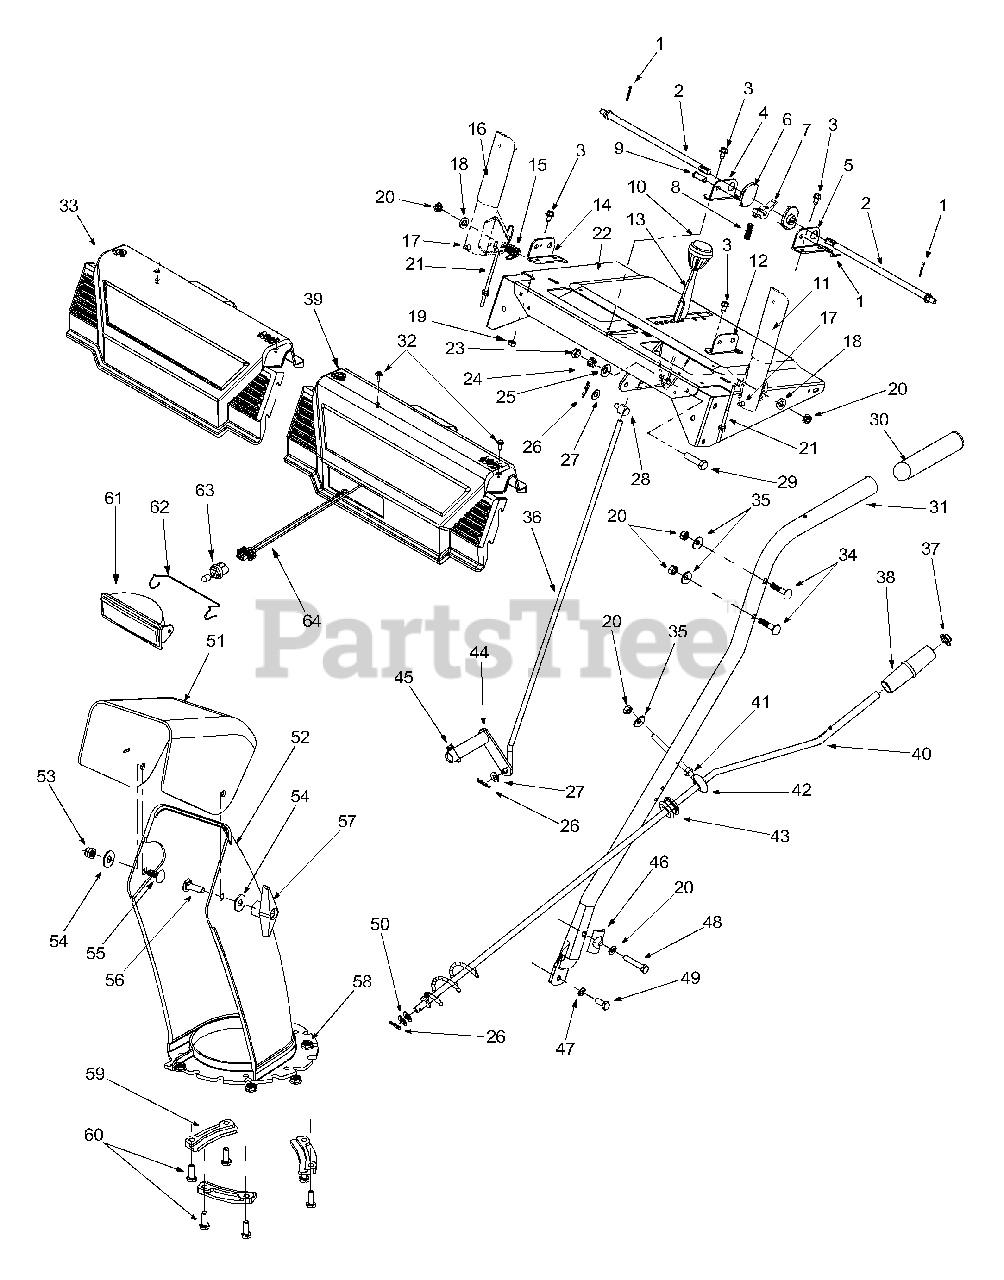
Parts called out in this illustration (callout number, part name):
1	Cotter Pin
3	Hex Washer Screw 1/4-20 x .5
6	Cam Lock Handle
7	Handle Lock Pawl
8	Compression Spring
9	Clevis Pin
10	Knob
11	Handle Assy - LH
15	Torsion Spring
16	Handle Assy - RH
17	Rubber Bumper
18	Washer
19	Hex Nut 1/4-20
20	Hex Nut 5/16-18
21	Cable
24	Compression Spring
25	Bell Washer
26	Cotter Pin
27	Flat Washer 5/16
28	Ferrule
29	Hex Cap Screw 3/8-24 x 1.50
33	Handle Panel (w/o lamp cut-out)
34	Carriage Bolt 5/16-18 x 1.50
35	Bell Washer .340 ID x .872 OD
36	Shift Rod
37	Push Cap
38	Chute Knob
39	Panel (w/ lamp cut-out)
40	Chute Crank
42	Chute Crank Eyebolt
43	Rubber Grommet
45	Hex Washer Screw 1/4-20 x 1.0
46	Handle Tab
47	Lock Washer 5/16
48	Hex Cap Screw 5/16-18 x 2
49	Hex Cap Screw 5/16-18 x .75
50	Flat Washer
51	Upper Chute
52	Lower Chute
53	Hex Lock Nut 5/16-18
54	5/16 Washer
55	Carriage Bolt 5/16-18 x .75
56	Carriage Screw 5/16-18 x 1.0
58	Hex Lock Nut 1/4-20
59	Flange Keeper
60	Hex Cap Screw 1/4-20 x .75
61	Lens Housing Assembly
62	Headlight Retaining Wire
63	Halogen Light
64	Light Harness
